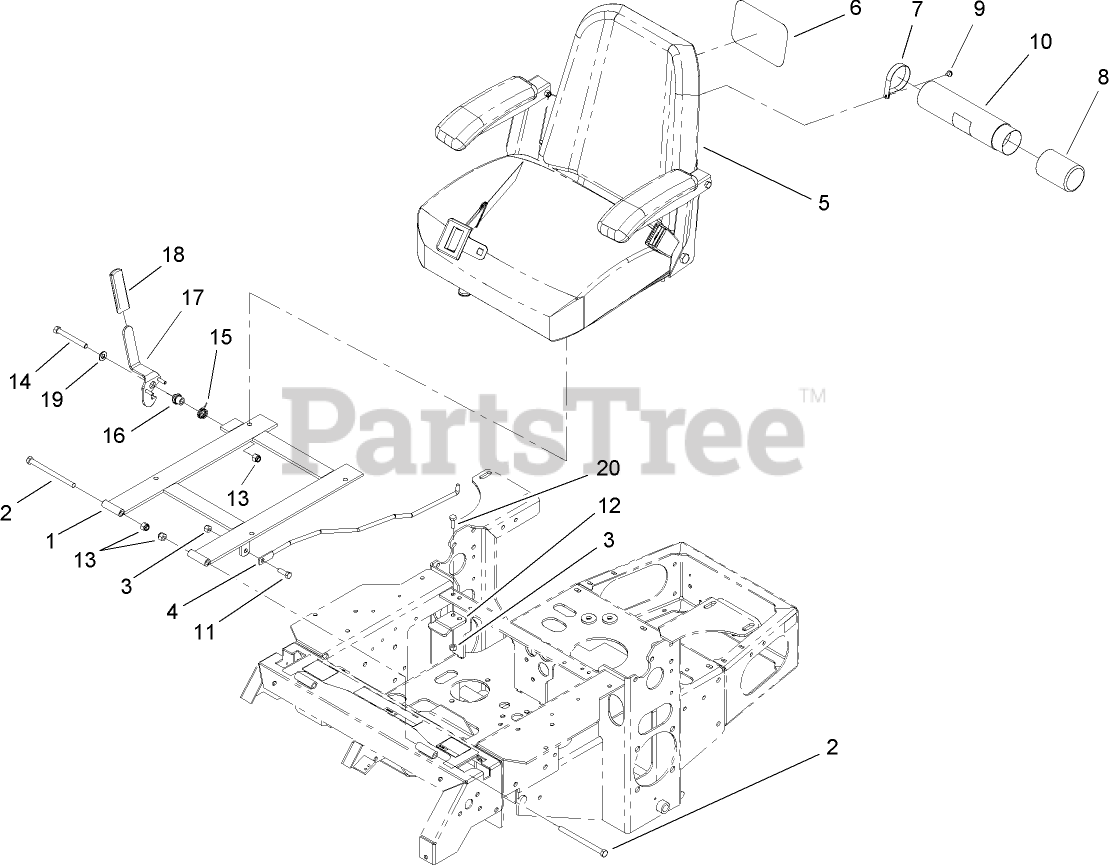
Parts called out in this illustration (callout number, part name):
1	SEAT SUPPORT FRAME ASM
2	SCREW-HH
3	NUT-LOCK, NI
4	ROD-RETAINER, SEAT
5	SEAT ASM
6	DECAL
7	CLAMP-R
8	CAP-HOUSING
9	SCREW-HWHTF
10	TUBE-MANUAL
11	SCREW-HH
12	CATCH-LATCH, SEAT
13	NUT-LOCK, NI
14	SCREW-HH
15	SPRING-TORSION
16	BUSHING-LATCH, SEAT
17	LATCH ASM
18	GRIP-HANDLE
19	WASHER-FLAT
20	SCREW-HH
